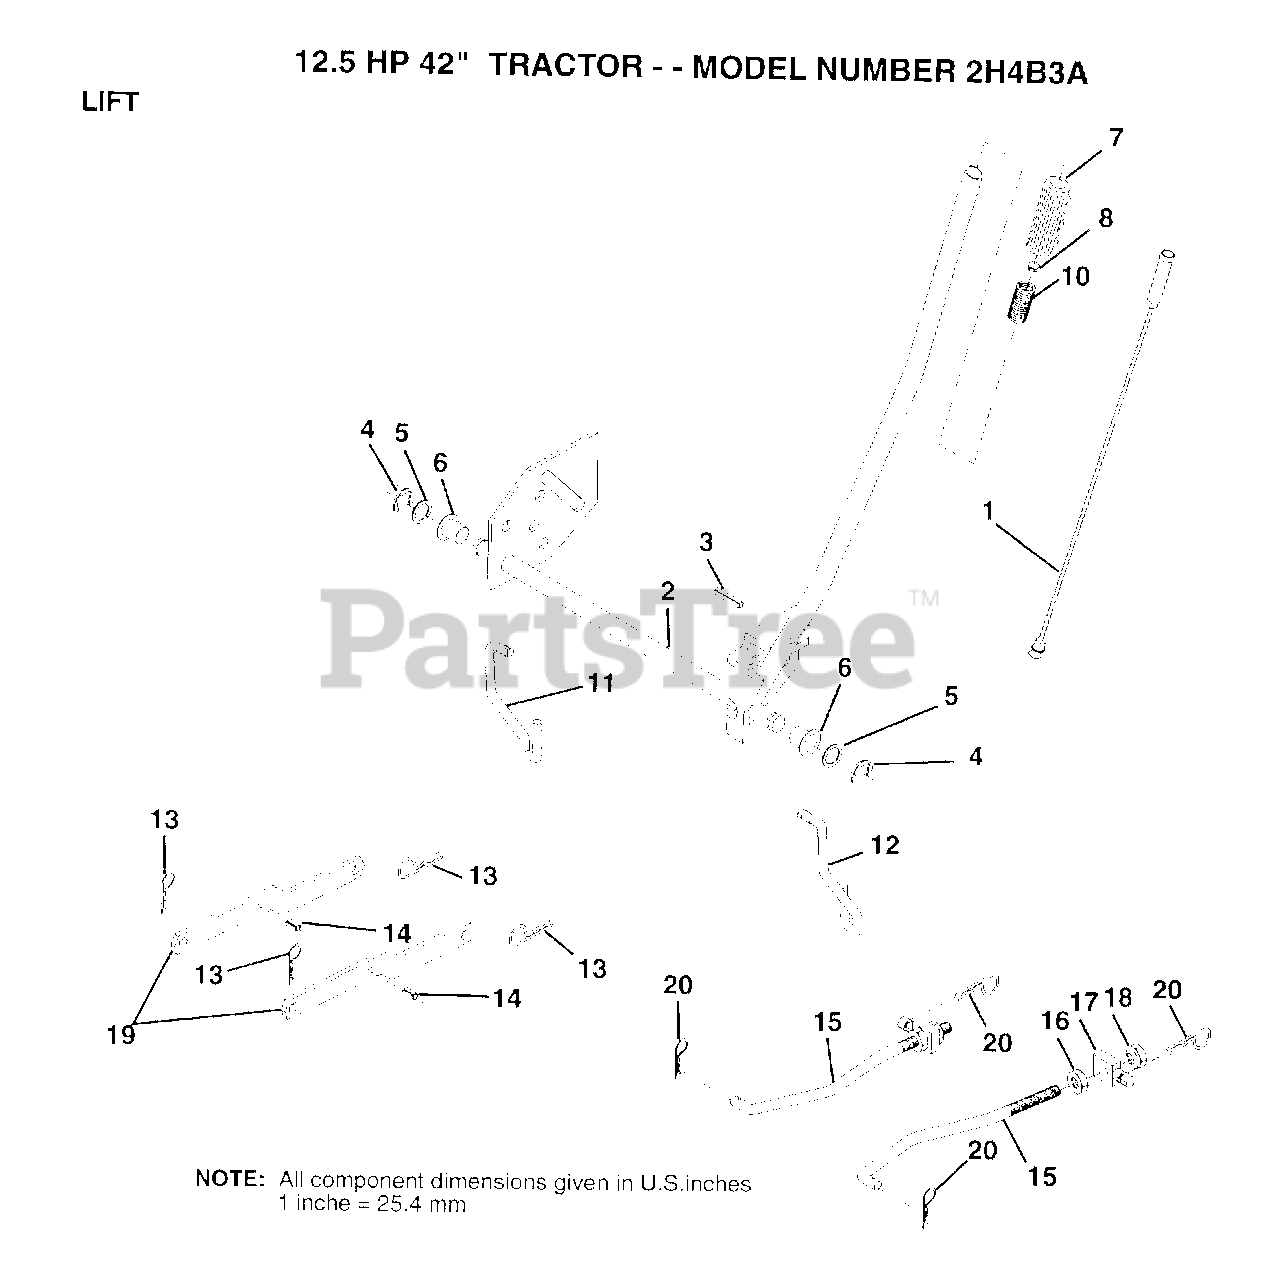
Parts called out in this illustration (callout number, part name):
1	WIRE ASM
3	PIN-GROOVE LT
5	WASHER
6	NYLON BEARING
7	GRIP
11	LINK LIFT LH
12	LIFT LINK RH
14	"PIN,SPRING"
15	LINK.FRONT
16	NUT
17	TRUNION
18	NUT.LK.W/WSH.1/2.
20	RETAINER.SPRING
